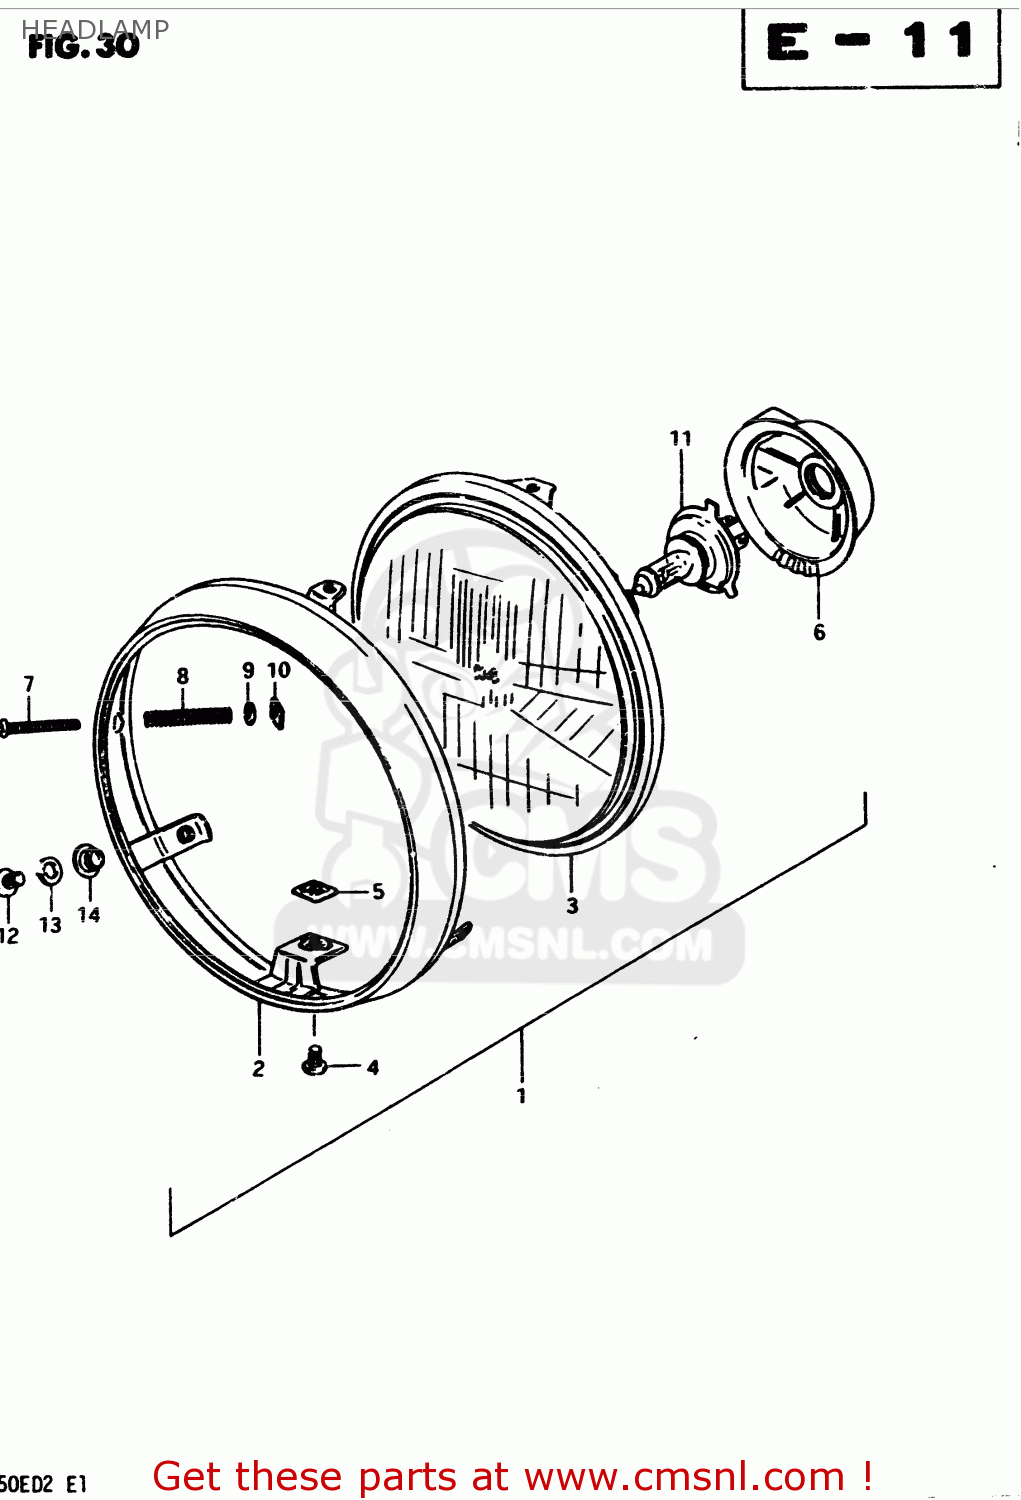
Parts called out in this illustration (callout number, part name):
1	HEADLAMP ASSEMBLY
2	RIM
3	LAMP UNIT
4	SCREW
5	NUT,ADJUSTING
6	COVER,SOCKET
7	SCREW,HEADLAMP ADJUST
8	SPRING
9	WASHER
10	NUT,HEADLAMP ADJUSTER
11	BULB(12V60/55W,H4)
12	SCREW
13	WASHER,LOCK
14	WASHER
